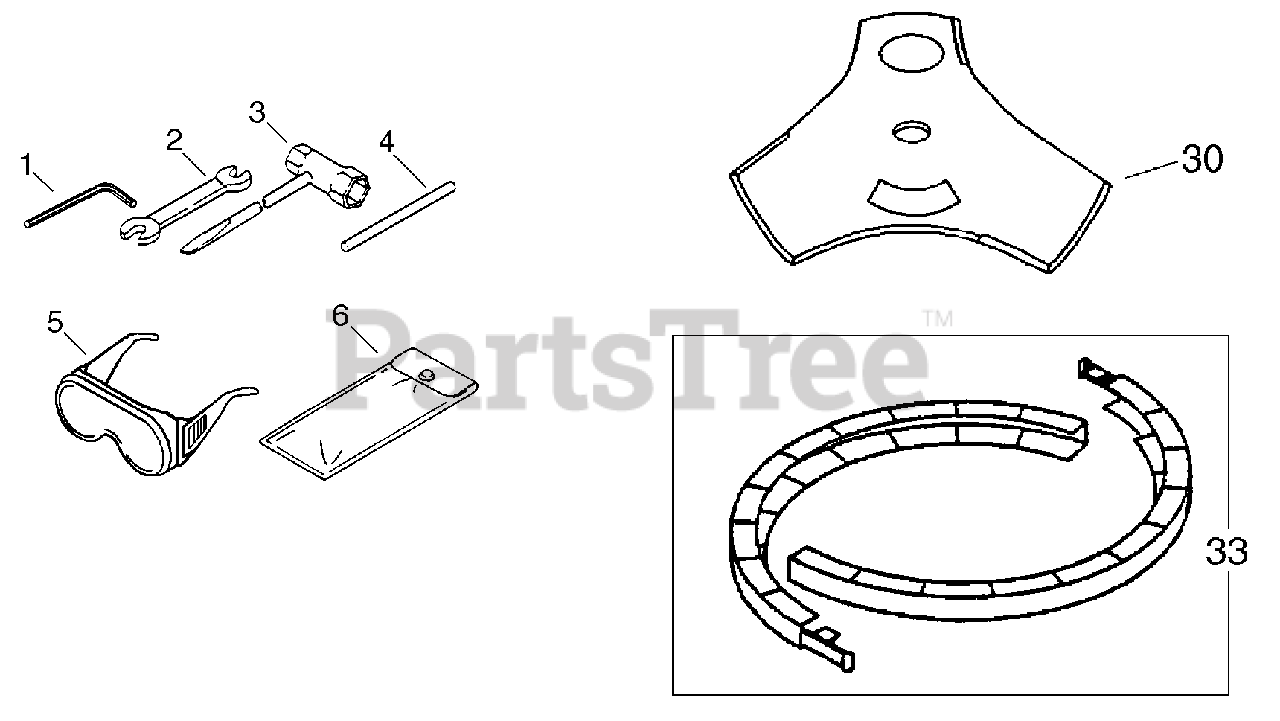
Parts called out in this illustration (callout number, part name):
1	HEX KEY - 4mm
2	SPANNER - 8X10mm
3	T-WRENCH - 17X19mm
4	LOCKING TOOL
5	GOGGLES
6	BAG, TOOL
30	BLADE - 3 TOOTH -- 25.4mm ID
33	COVER, BLADE
